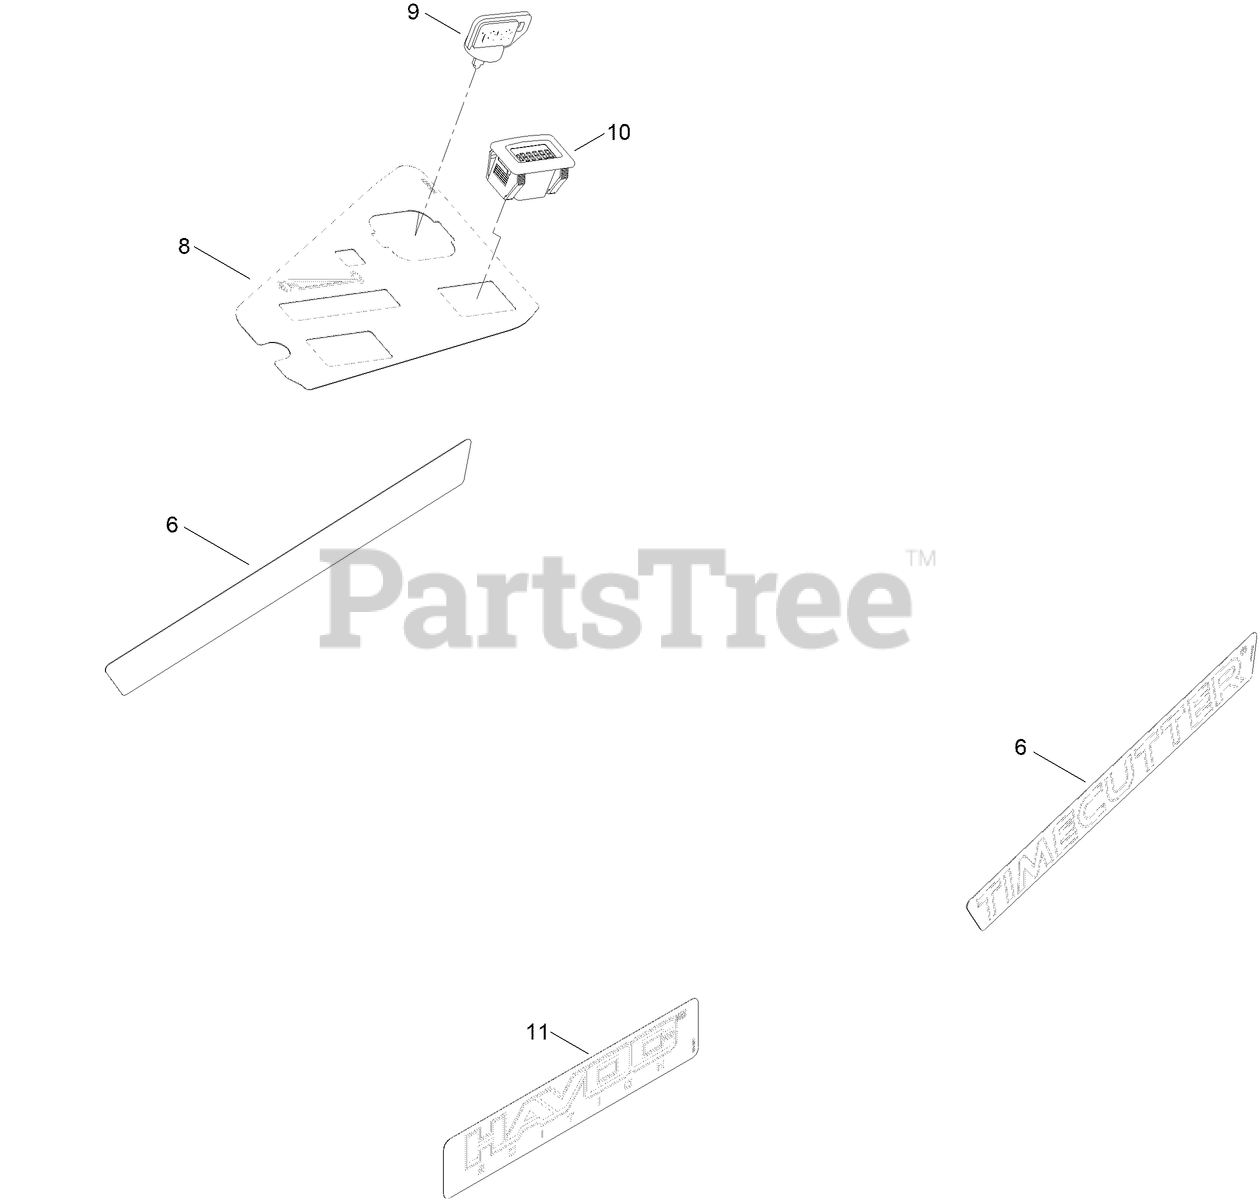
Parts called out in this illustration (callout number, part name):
6	DECAL - TIMECUTTER
8	DECAL - CONTROL PANEL
9	KEY-IGNITION
10	HOUR METER
11	DECAL-HAVOC
